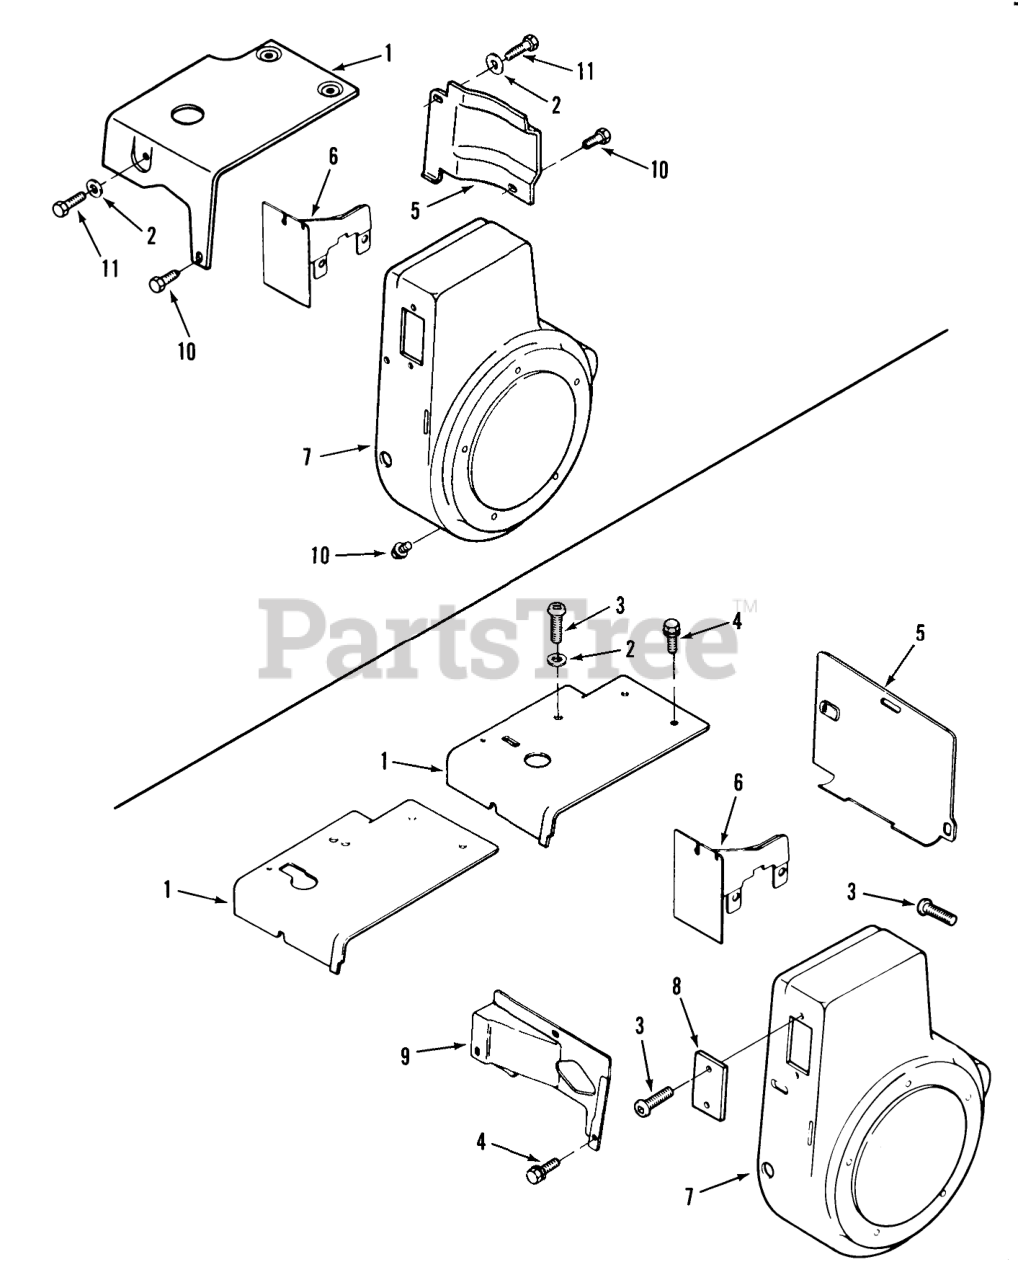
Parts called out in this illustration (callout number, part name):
1	Head Baffle 308 Only
2	Washer
3	Screw-Pozidriv T.H.
4	Screw Hex Hd
5	Cylinder Baffle 308
6	Inner Baffle 308 Only
7	Blower Housing 308
8	Cover 310 Only
9	Baffle-SideAir
10	Screw
11	H.C. Sems Screw 1/4-20 x 3/4
